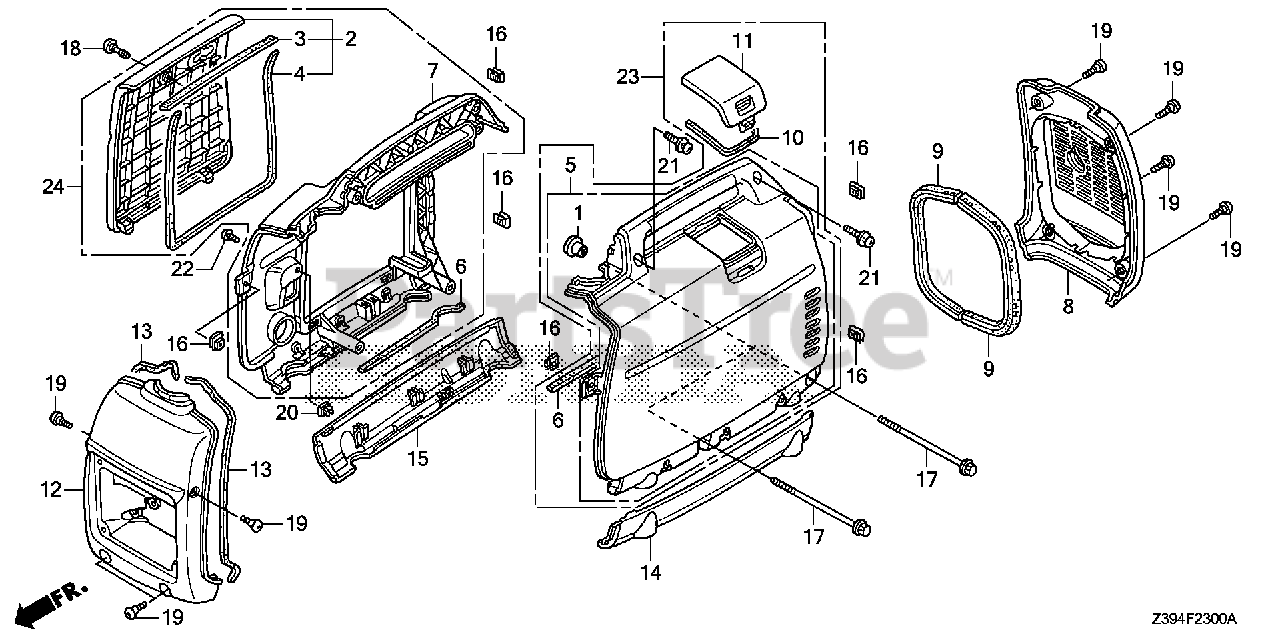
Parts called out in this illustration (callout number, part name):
1	COLLAR, FAN COVER
2	COVER ASSY., MAINTENANCE *R280* (POWER RED)
3	SEAL A, MAINTENANCE COVER
4	SEAL B, MAINTENANCE COVER
5	COVER, SIDE *R280* (POWER RED) (L. SIDE)
6	SEAL A, SIDE COVER
7	COVER, SIDE *R280* (POWER RED) (R. SIDE)
8	COVER, RR. *NH314* (CONDUCT GRAY)
9	RUBBER, RR. COVER SEAL
10	SEAL, PLUG CHECK
11	COVER, PLUG CHECK *R280* (POWER RED)
12	COVER, FR. *NH314* (CONDUCT GRAY)
13	SEAL, FR. COVER
14	PLATE, SIDE (LOWER) *NH314* (CONDUCT GRAY) (L. SIDE)
15	PLATE, SIDE (LOWER) *NH314* (CONDUCT GRAY) (R. SIDE)
16	NUT, FENDER SETTING
17	BOLT, FLANGE (6X137)
18	SCREW, SPECIAL (6X16)
19	SCREW, SPECIAL (6X15)
20	GROMMET, SCREW (6MM)
21	SCREW-WASHER (6X20)
22	SCREW, TAPPING (5X16) (PO)
